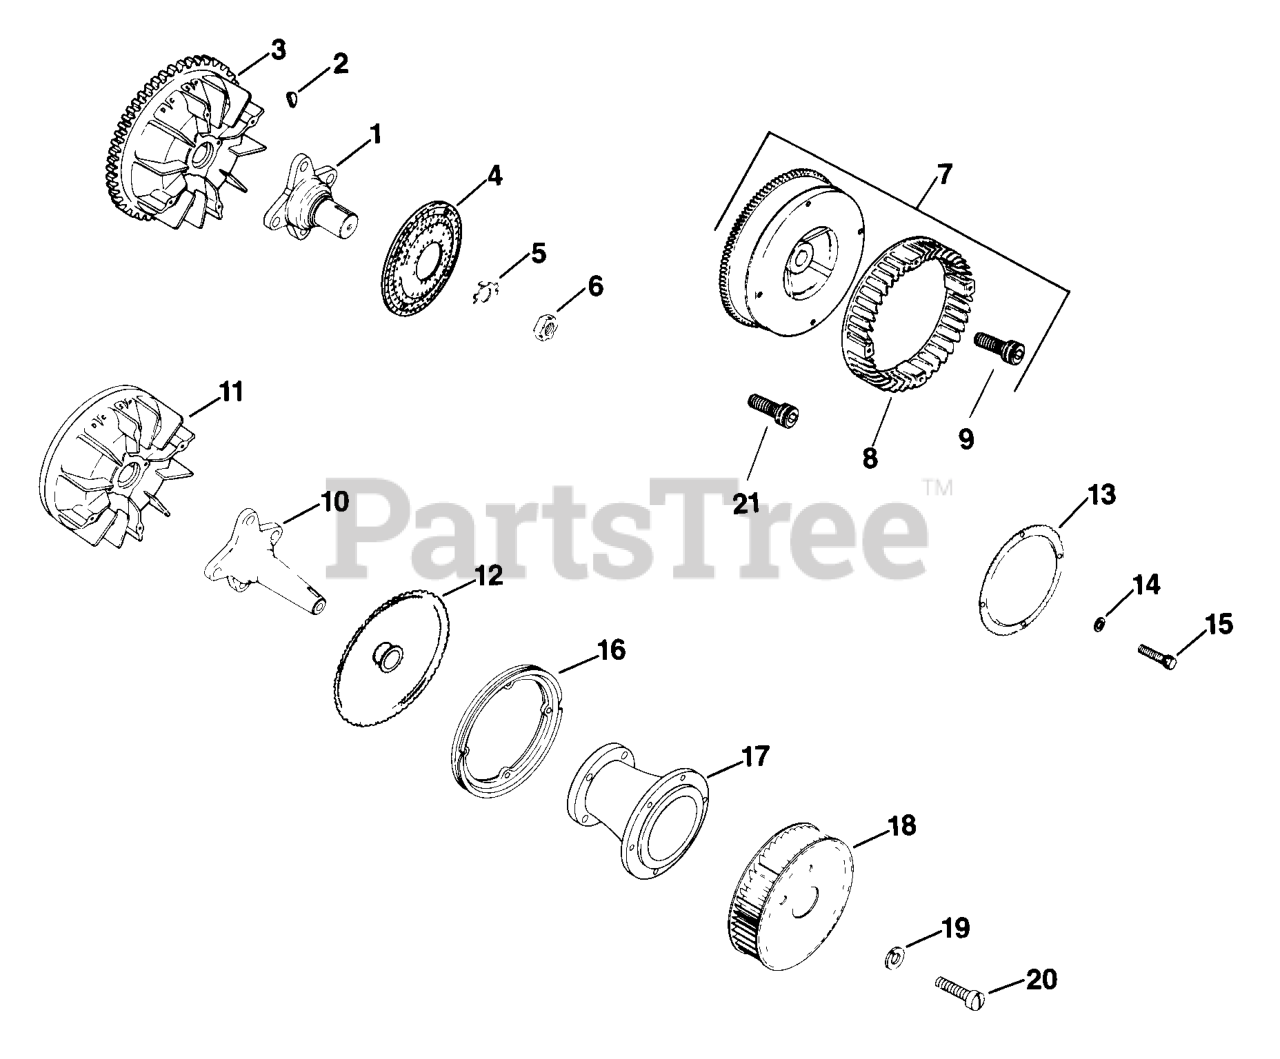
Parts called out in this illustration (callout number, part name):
2	KEY, 1/4" X 1"
3	FLYWHEEL - DISCONTINUED
4	SCREEN - DISCONTINUED
5	LOCK, NUT - (#DSC)
6	NUT, JAM 1-14 GRADE 2 USE 25 100 28-S
14	WASHER, FLAT 1/4"
20	SCREW, POZ TRS HD 1/4-20X5/8" - DISCONTINUED
